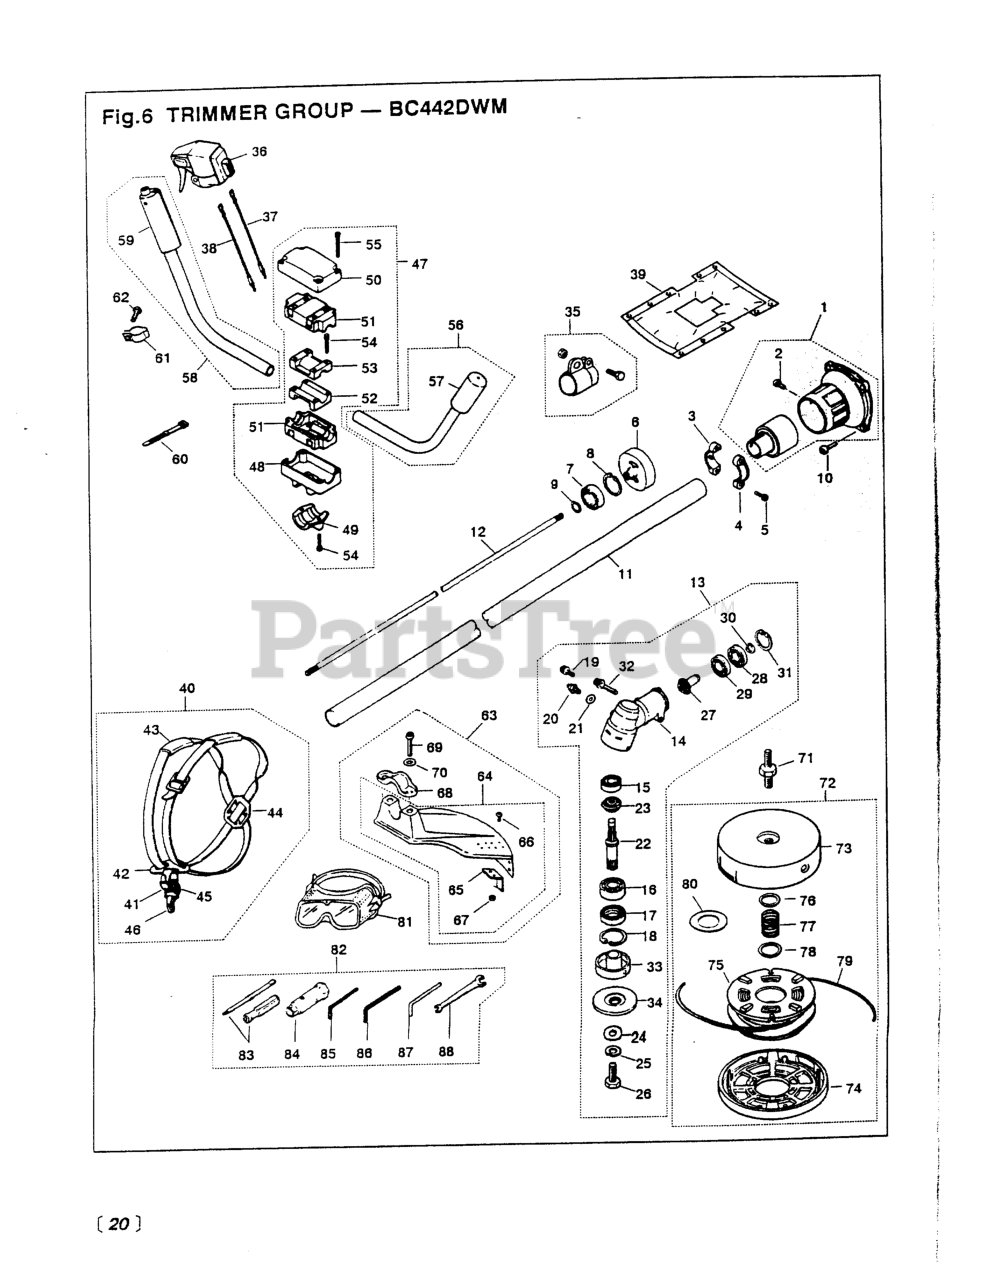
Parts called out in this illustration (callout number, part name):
1	HOUSING COMPLETE
2	SCREW, M6 x 10
4	CLAMP (B)
5	BOLT
6	DRUM, SPLINED
7	BEARING
8	RING, SNAP, M35 X 1.5
9	RING, SNAP, M15 X 1.0
10	BOLT, M6 X 20
12	SHAFT (USE 6340-12211)
13	GEARCASE ASSY (RPLS -13001)
14	GEARCASE (RPLS -13113)
15	BEARING (RPLS T3403-13510)
18	RING, SNAP, M35 X 1.5
19	BOLT, M5 X 10
20	FITTING, GREASE
21	WASHER, M6 X .8
22	SHAFT (RPLS -13211)
24	WASHER, M10 x 3.2
25	WASHER
26	BOLT (REPLACES 3130-13260)
28	BEARING
29	BEARING
31	RING, SNAP, M28 x 1.2
32	BOLT, M6 x 1.35
33	HOLDER (A) (RPLS -13240)
34	HOLDER (B)
35	HANGER COMPLETE
36	LEVER ASSEMBLY
37	CORD A (RED)
38	CORD (RPLS -14720)
43	PROTECTOR
49	CAP, LOWER
50	CAP, UPPER
51	ABSORBER
52	CLAMP (A)
53	CLAMP (B)
54	BOLT, M5 X 25
55	BOLT, M5 X 30
56	HANDLE COMPL, LEFT
58	HANDLE COMPL, RIGHT
59	GRIP
60	BAND
61	CLAMP
62	SCREW, M5 X 16
65	BLADE
66	SCREW, M5 x 12
67	NUT
68	CLAMP
69	BOLT, M6 x 1.30
70	WASHER, M6 X 15
71	ARBOR, 10MM
72	6
74	COVER
76	PLATE, LARGE
78	PLATE, SMALL
79	CORD
80	SPACER
83	SCREWDRIVER
85	WRENCH (TOOL)
86	WRENCH (TOOL)
87	BAR
88	SPANNER, 8 X 10 (RPLS 2540- )
